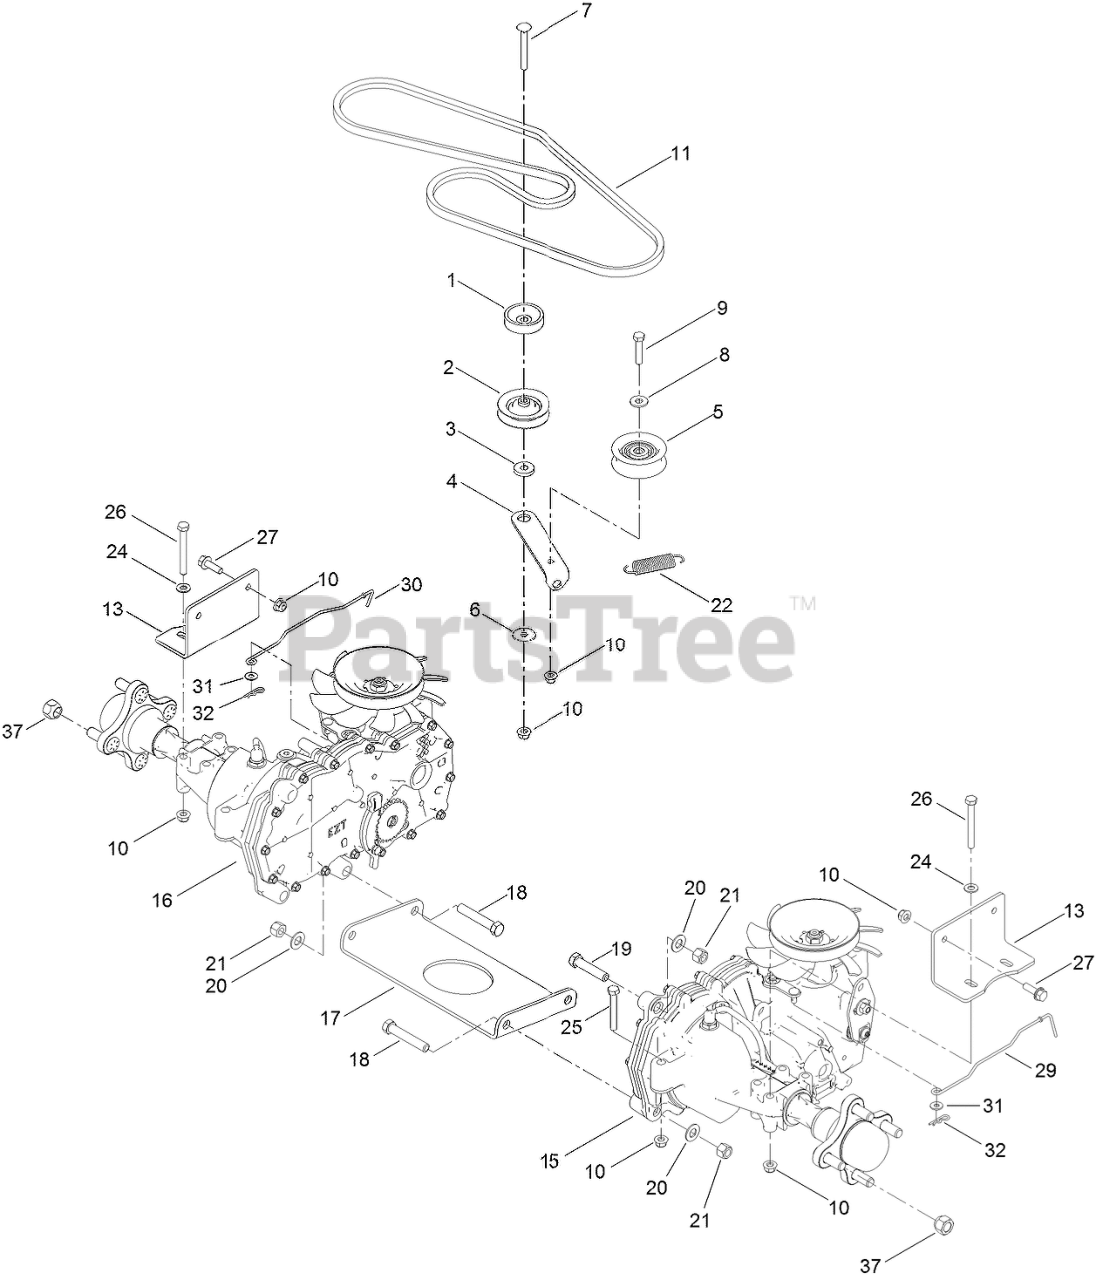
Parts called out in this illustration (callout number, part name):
1	SPACER
2	PULLEY-IDLER
3	SPACER-ARM, IDLER
4	ARM-IDLER
5	PULLEY-IDLER, FLAT
6	WASHER-PIVOT
7	SCREW-CARR
8	WASHER-FLAT
9	SCREW-HH
10	NUT-HF, NI
11	V-BELT
13	MOUNT-HYDRO
15	LH HYDRO TRANSAXLE ASM
16	RH HYDRO TRANSAXLE ASM
17	PLATE-CROSS, HYDRO
18	SCREW-HH
19	SCREW-HH
20	WASHER-FLAT
21	NUT-LOCK, NI
22	SPRING-PEDAL, RETURN
24	WASHER-PLAIN
25	SCREW-HH
26	SCREW-HH
27	SCREW-HHF
29	ROD-BYPASS, LH
30	ROD-BYPASS, RH
31	WASHER
37	NUT-LUG
